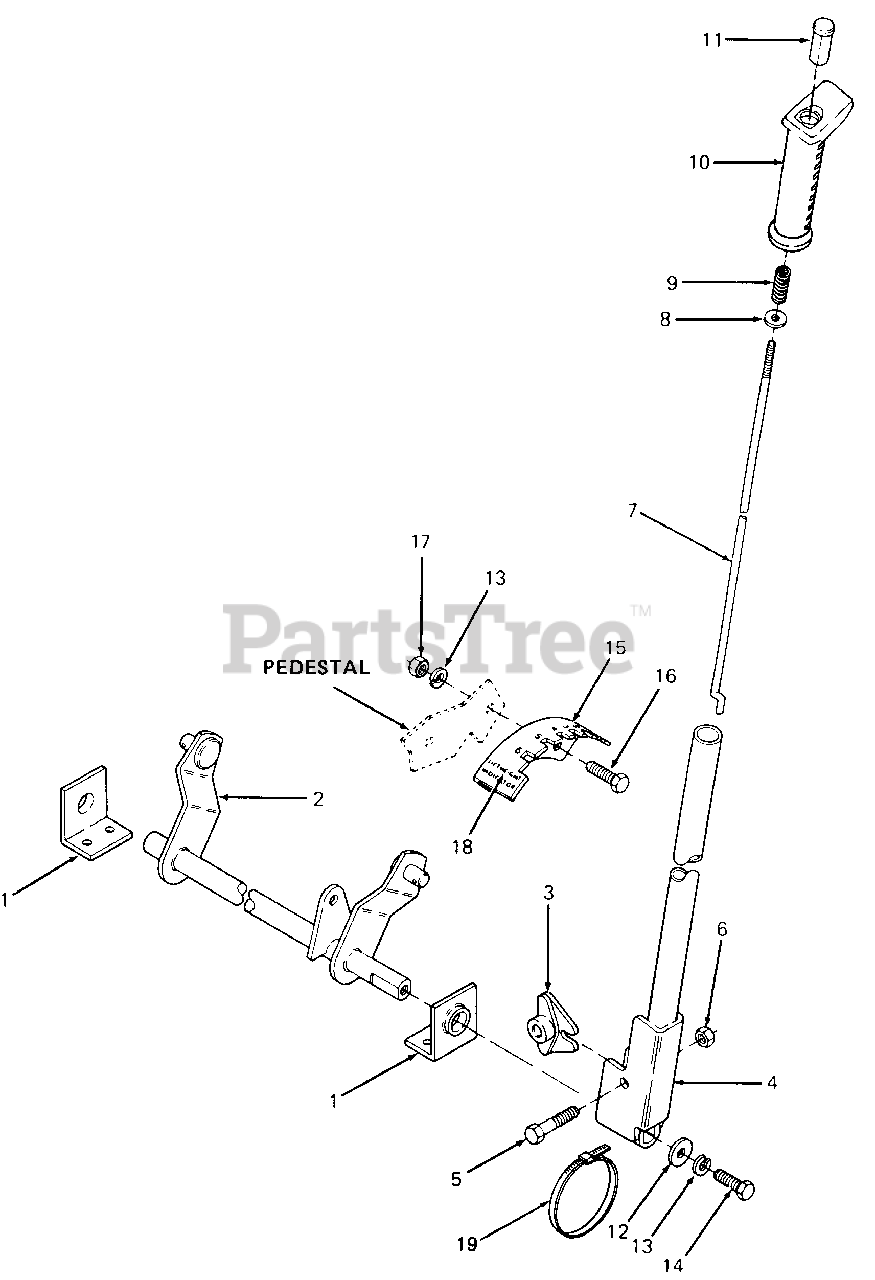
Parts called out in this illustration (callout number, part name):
1	Bracket, Lift Shaft
2	Shaft Assy, Lift
3	Kit, Index Pawl
4	Handle, Lift
5	Screw, Hex, 3/8-16 X 1.62 Lg
6	Nut, Hex Center Lock Jam, 3/8-24
7	Rod, Index
8	Washer, Flat, .260 X .720 X .06
10	Grip, Lift Handle
11	Button, Handle
12	Washer, Flat, .345 X 1.0 X .100 Thk
13	Washer, Lock, 5/16
14	Screw, Hex Cap, 5/16-24 X .75 Lg
17	Nut, Hex, 5/16-18 GR5
18	Label, Height Indicator
19	Tie, Cable
